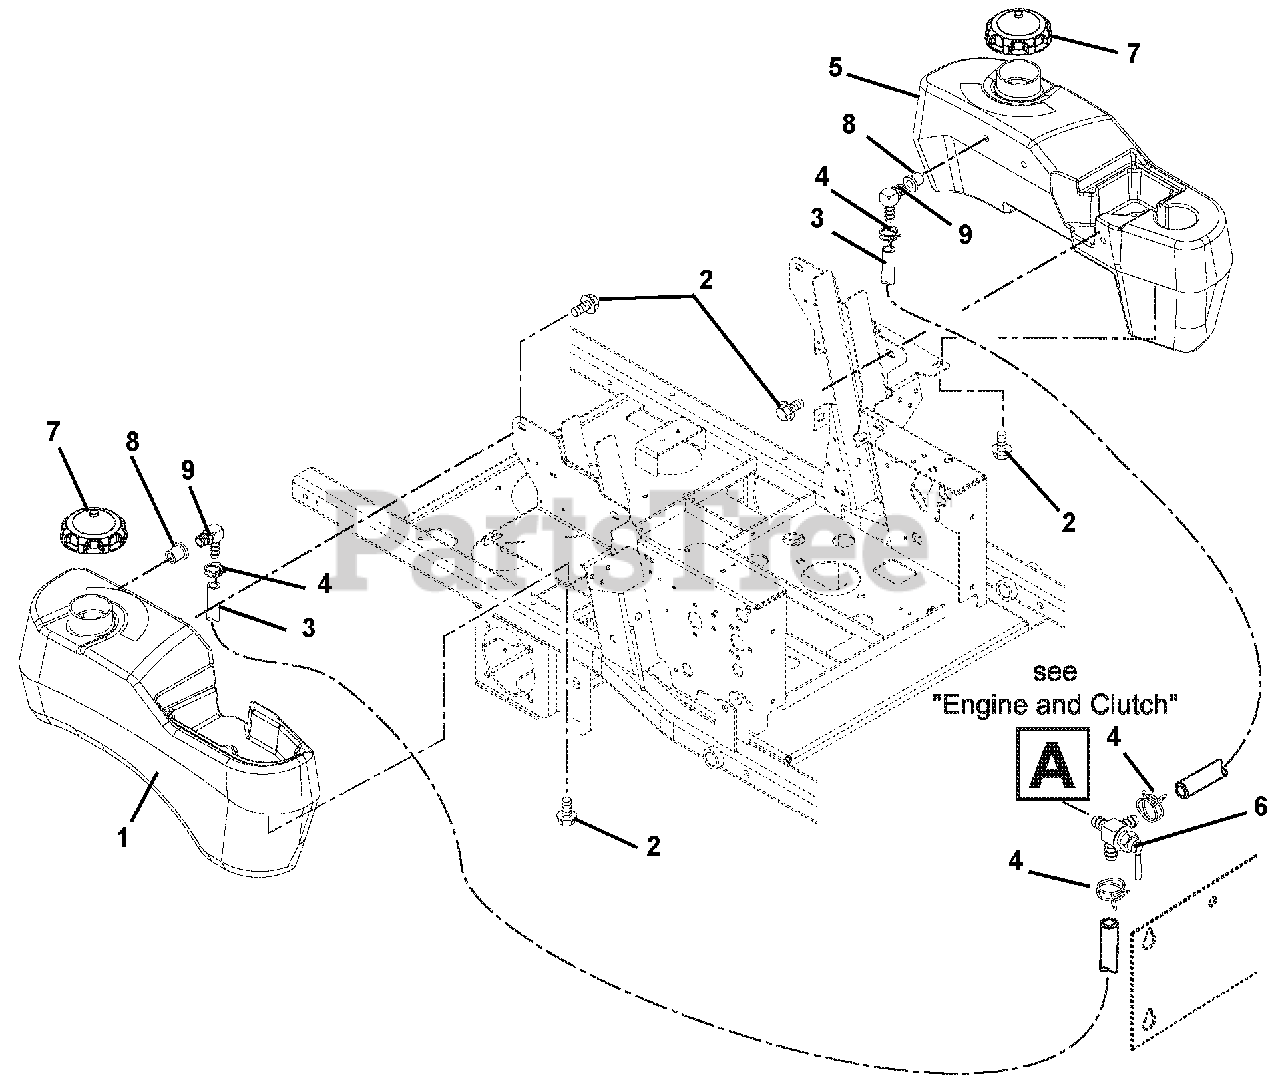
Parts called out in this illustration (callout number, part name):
1	Tank, Fuel - Right Hand
2	Bolt, SEMS .31-18 x .62
3	Gas Line, Bulk .25 I.D. (2 @ 42 in.) (045, 046, 047, 025, 066, 067, 068, 071, 087, 088, 089, 102)
4	Clamp, Hose Wire .49/.51 x .116
5	Tank, Left Hand Fuel (EYE-Q)- 200 Series
6	Valve, Fuel
7	Cap, Gas
8	Grommet (Black in color. Does not replace or interchange with orange colored grommet.)
9	Tank Fitting
